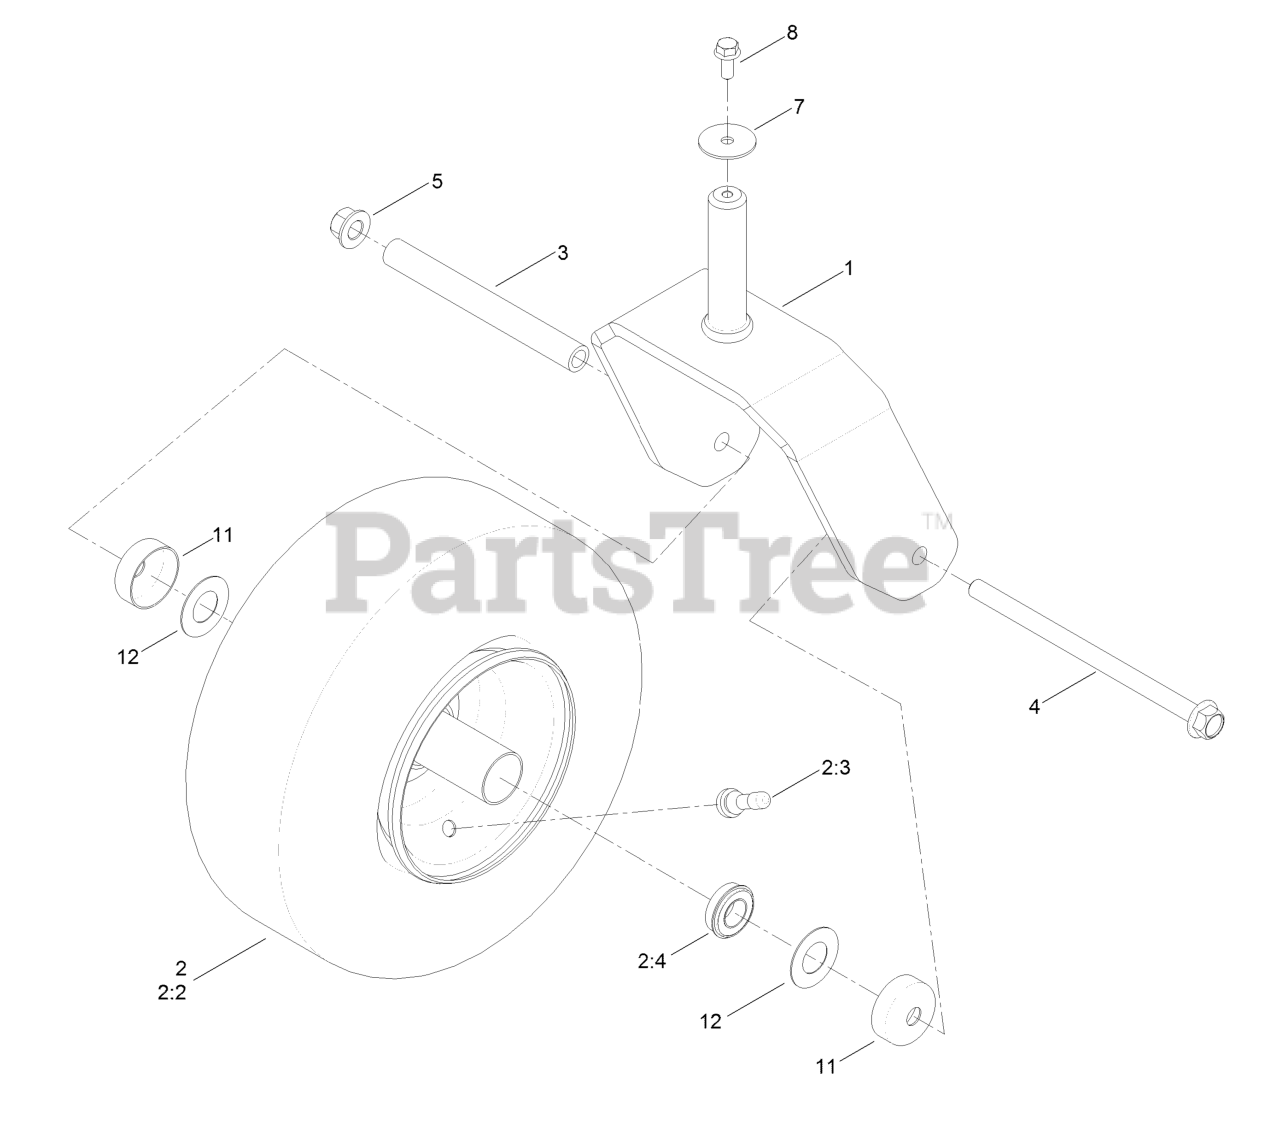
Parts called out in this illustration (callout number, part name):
2	TIRE AND WHEEL ASM
2:3	Stem-Valve
2:4	BEARING
3	SPANNER-WHEEL
4	SCREW-HHF
5	Nut-Lock 1/2-13
7	WASHER-FLAT
8	SCREW-HHF
11	GUARD-SEAL
